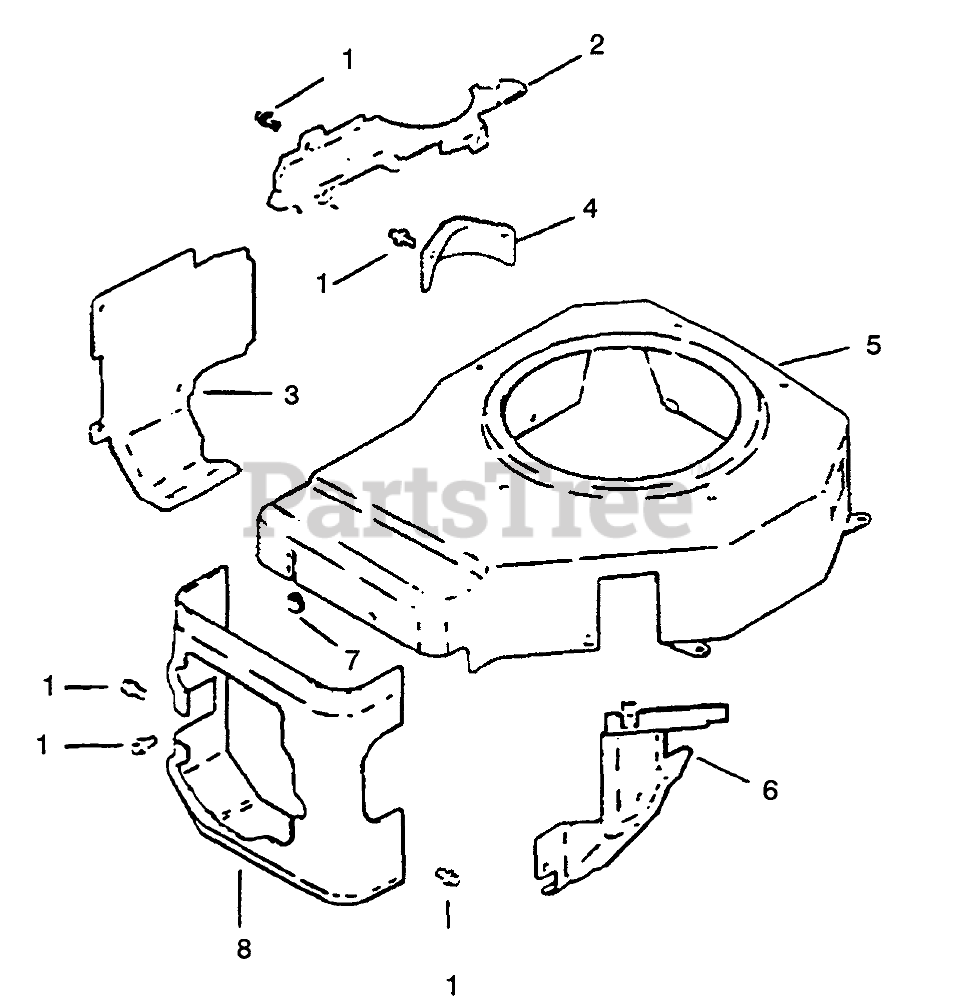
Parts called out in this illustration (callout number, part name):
1	Screw
2	Plate-Blower Housing
3	Baffle-Cylinder
4	Cover-Starter
5	Housing-Blower
6	Baffle-Carburetor
7	Grommet-Blower
8	Baffle-Cyl. Head
